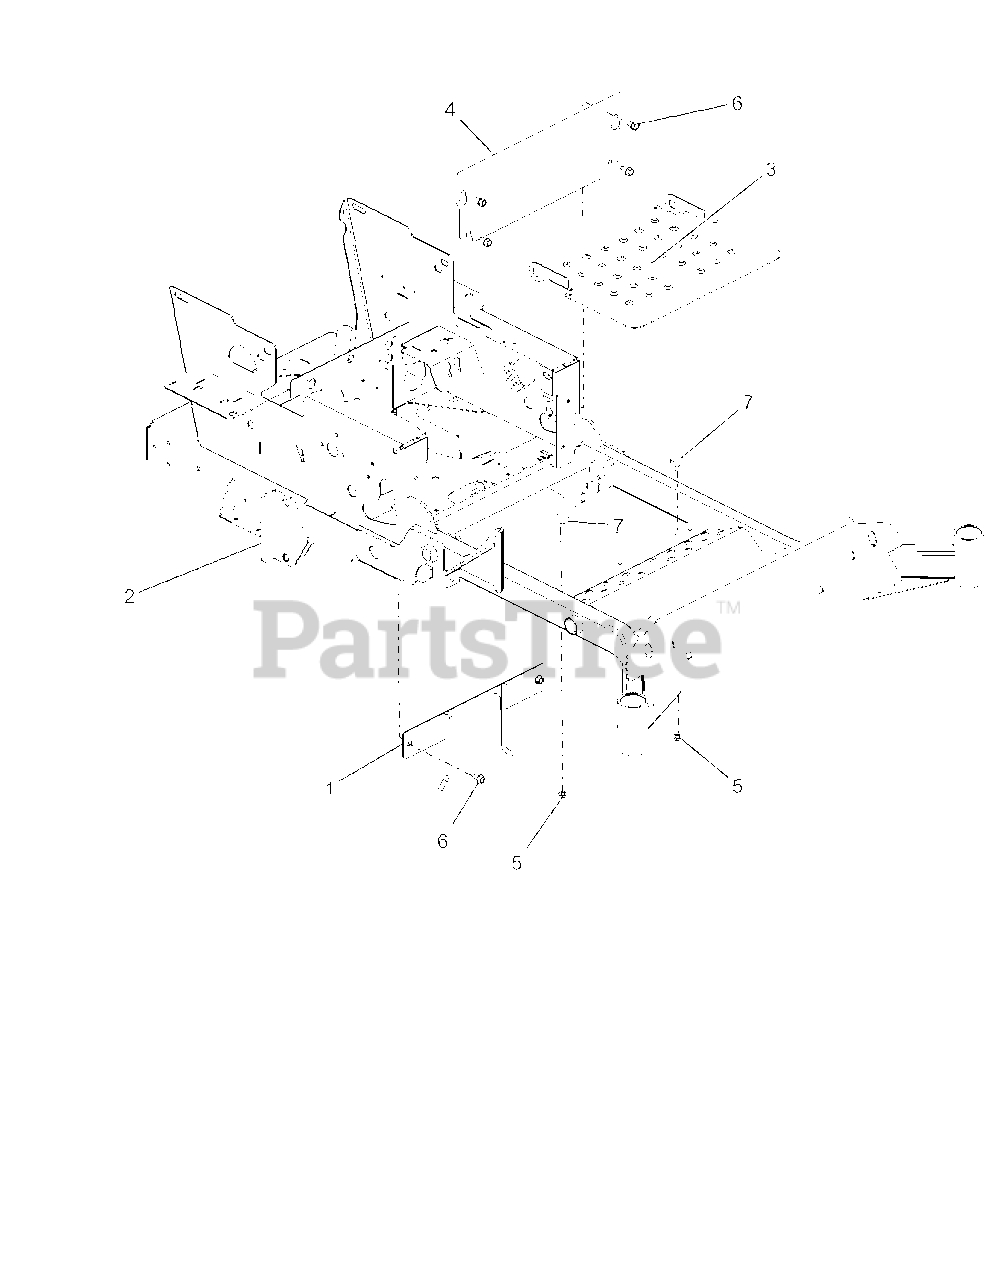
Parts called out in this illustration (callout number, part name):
1	WLDMT, PTO BELT FINGER-BLACK
2	WLDMT, 52"-60" HD FRAME
3	PANEL, INSPECTION
4	PLATE, KICK (RED)
5	@NUT-SPNLK-FLG .312-18 YWZC
6	SCR-TAP .38-16X.75 HWH TR YWZ
7	BUMPER, RUBBER
